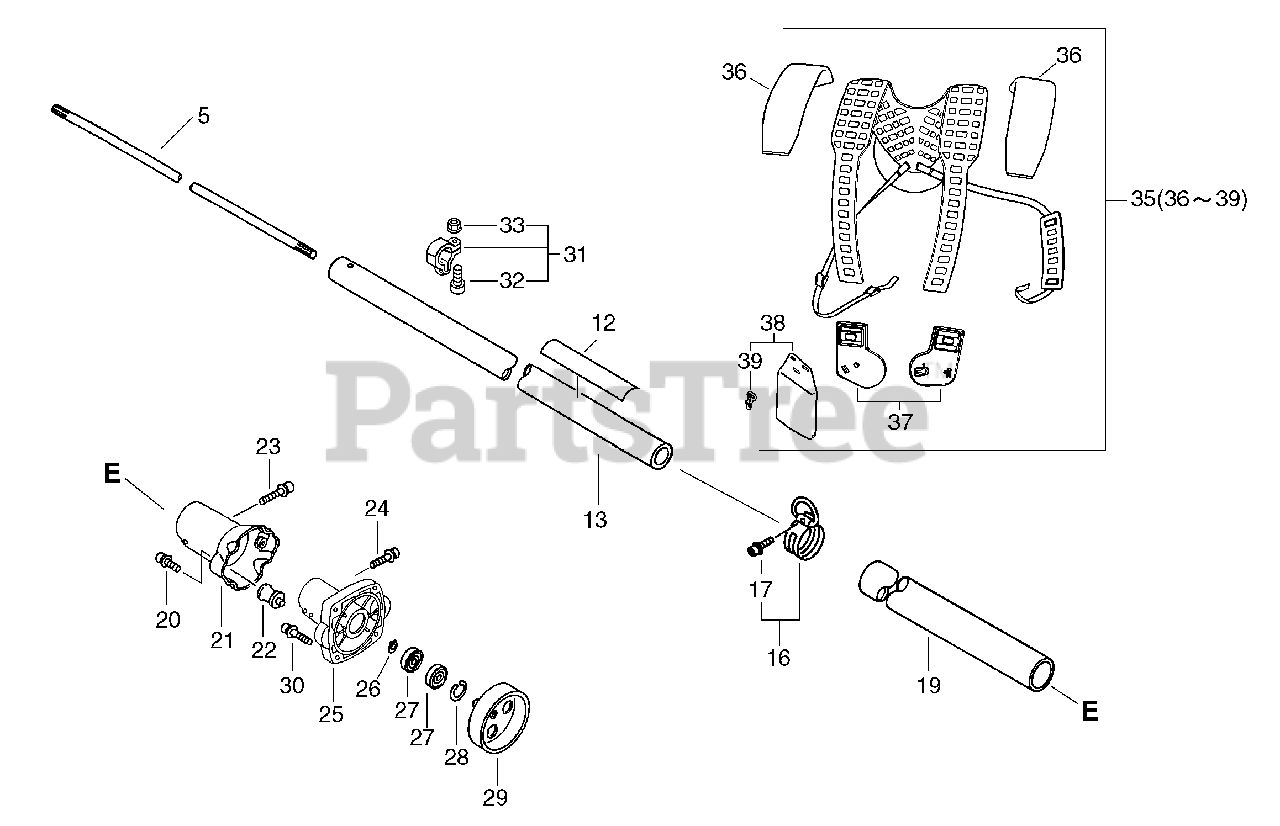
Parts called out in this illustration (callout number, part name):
5	DRIVESHAFT
12	LABEL, CAUTION
13	MAIN PIPE ASSY
16	HANGER KIT
17	BOLT 5×20
19	PIPE, MAIN
20	BOLT 5×14
21	COVER, FAN
23	BOLT M5×35
24	BOLT 5×30
25	CASE, CLUTCH
26	RING, RETAINING 15
27	BEARING, BALL 6203
28	RING, SNAP 35
29	DRUM, CLUTCH
30	BOLT 5×25
32	BOLT 5×22
33	NUT, FLANGE M5
35	SHOULDER STRAP ASSY
36	PAD, SHOULDER
37	PLATE, LOCK
38	PAD, HIP
39	HOOK
